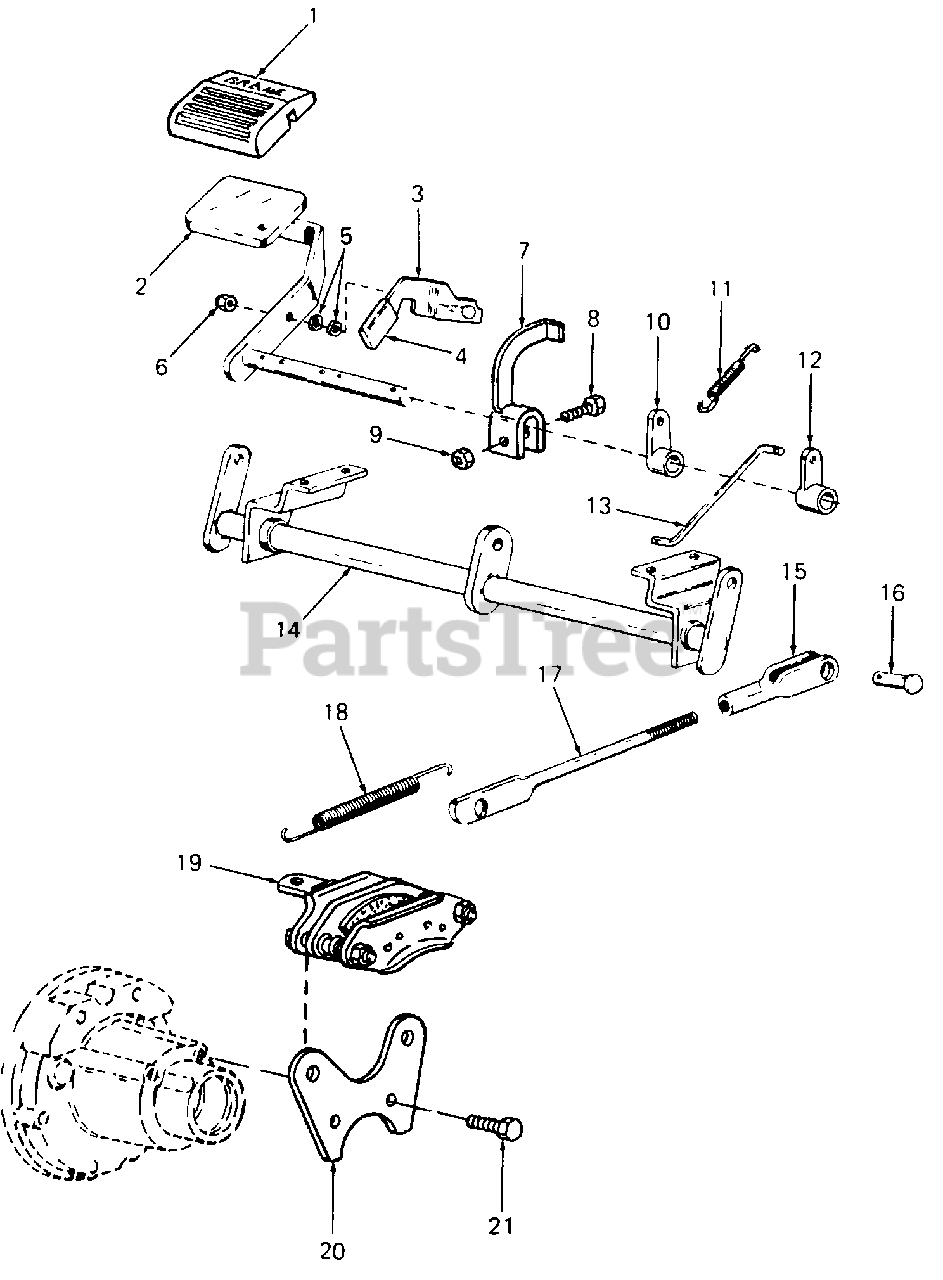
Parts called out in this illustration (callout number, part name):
1	Pad, Brake Pedal
2	Pedal Assy, Brake
5	Washer, Wave, 1/4 Dia
6	Nut, Hex Insert Lock, 1/4-20
9	Nut, Hex Center Lock, 1/4-20
11	Spring, Return
15	Clevis, Adjustment
16	Pin, Clevis, 3/8 Dia X 1.0 Lg
17	Rod, Brake
18	Spring, Tension
19	Kit, Brake Caliper
20	Bracket, Brake Mounting
21	Screw, Hex Cap, 5/16-18 X 1.0 Lg GR5
